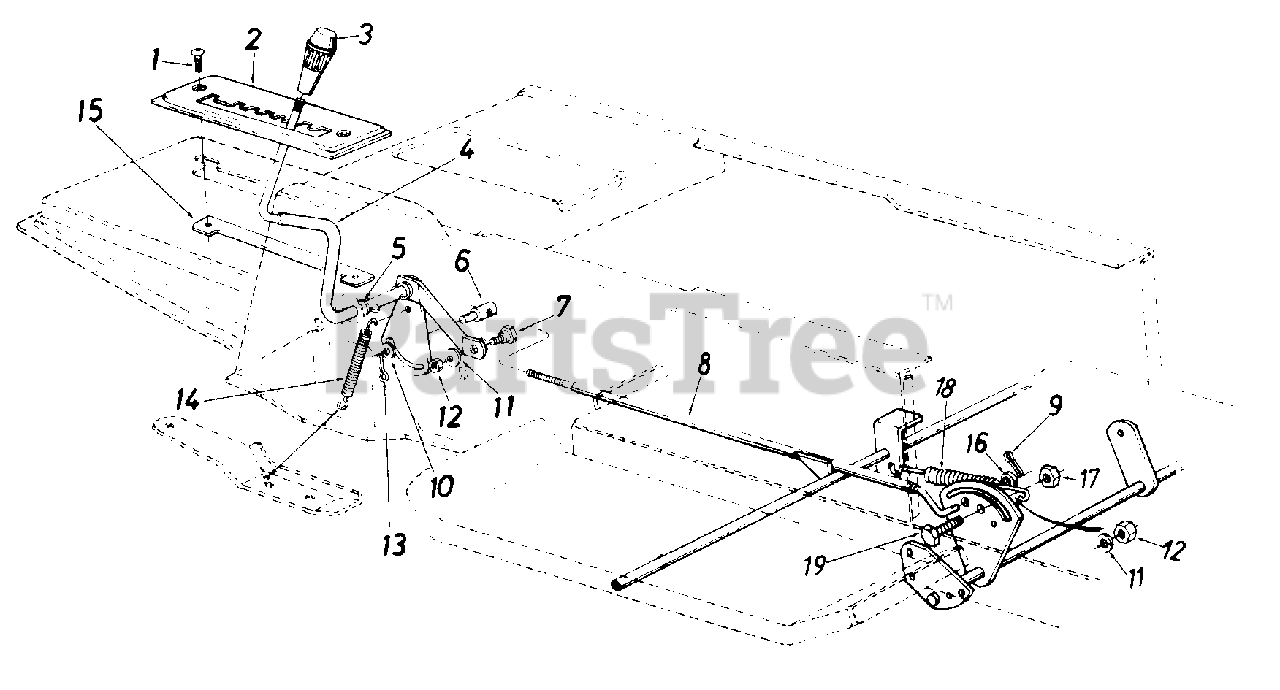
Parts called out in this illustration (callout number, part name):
1	Truss Mach. Scr. 1/4-20 x .75" Lg.
4	Speed Selector Cam Ass'y.
5	Flat Washer .53" I.D. x .93"
6	Ferrule 3/8-24 x .37" Dia.
7	Shoulder Bolt .435" Dia. x .160
8	Speed Control Rod Ass'y.
9	Cotter Pin 3/32" Dia. x .75"'
10	Fl-Wash. .385" I.D. x .62" O.D.
11	L-Wash. 5/16" I.D.
12	Hex Nut 5/16-18 Thd.
13	Cotter Pin 3/32 Dia. x .75"
14	Spring
15	Clamping Plate
16	Fl-Wash. .47" I.D. x .88" O.D.
17	Hex L-Nut 5/16-18 Thd.
18	Ext. Spring 4.75" Lg.
19	Hex Bolt 5/16-18 x 1" Lg. (Grade 5)
